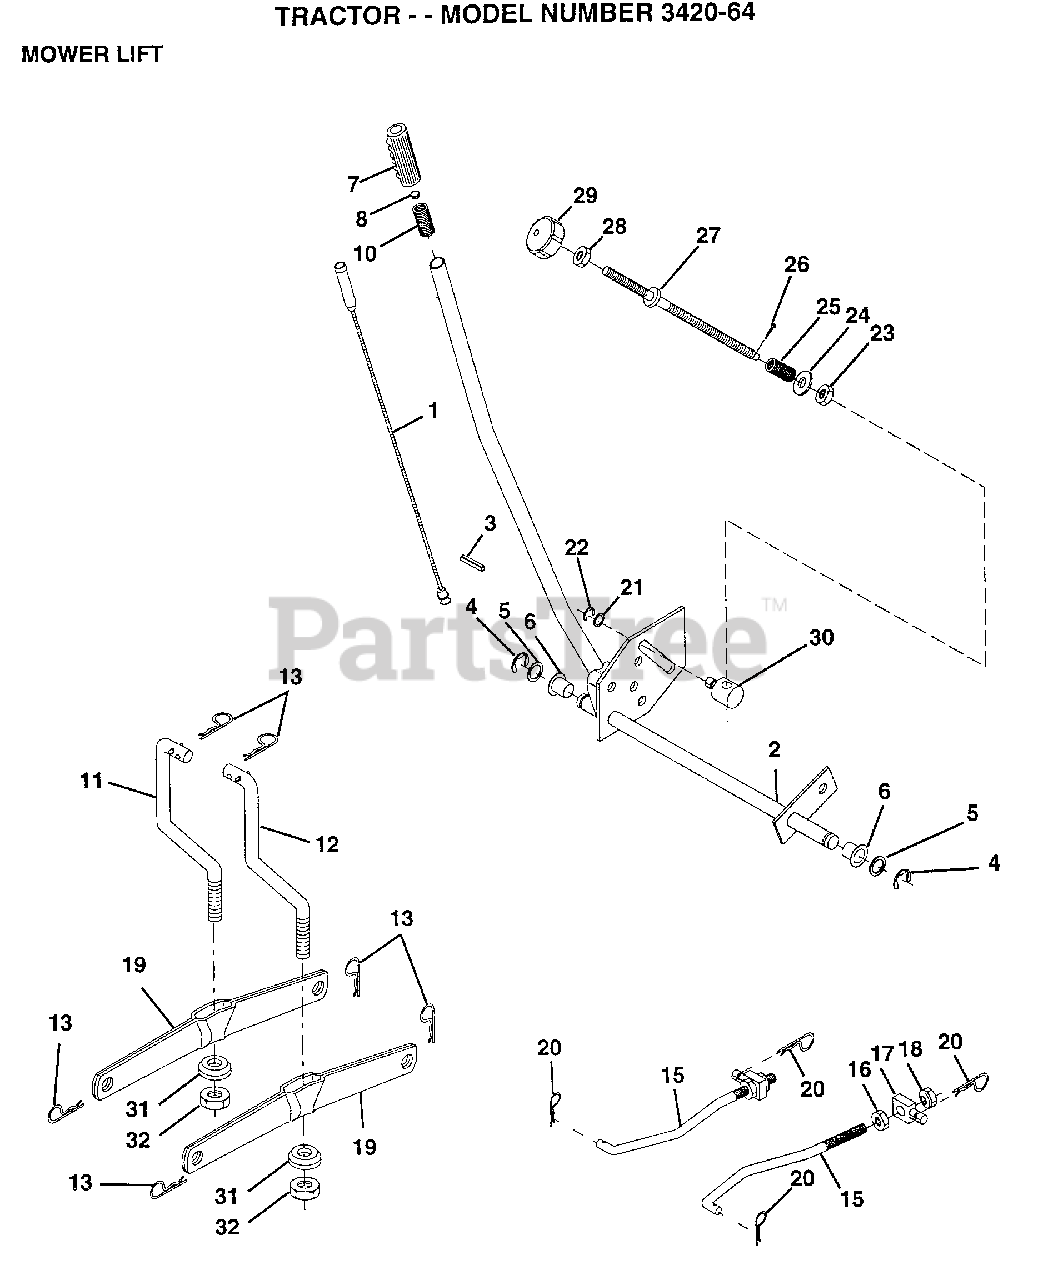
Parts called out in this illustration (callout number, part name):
1	WIRE ASM
2	SHAFT.ASM.LIFT
3	PIN GROOVE
5	WASHER
6	NYLON BEARING
7	GRIP
15	LINK.FRONT
16	NUT
17	TRUNION
18	NUT.LK.W/WSH.1/2.
19	ARM SUSP REAR
20	RETAINER.SPRING
23	NUT T
24	WASHER
25	SPRING.COMP.INF.H
27	ROD.ADJ.LIFT
28	NUT
29	KNOB INF 3/8-16
30	TRUNNION
31	BEARING PVT LH
32	NUT.CROWNLOCK.3/8
49	NUT.HXFLG.LOCK.
